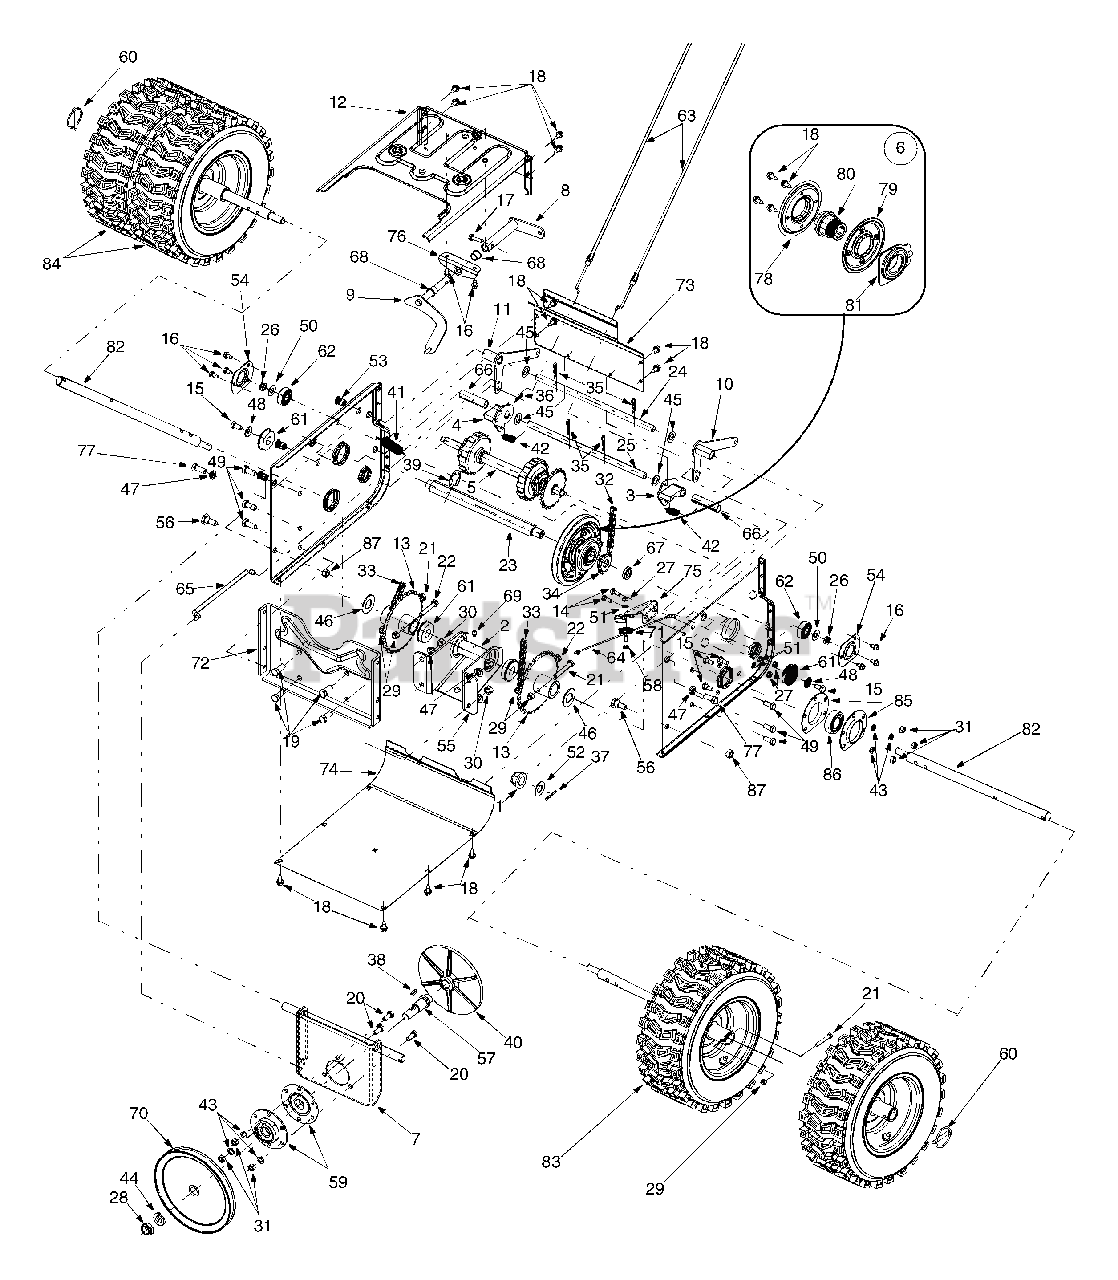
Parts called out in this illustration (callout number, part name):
1	Hex Flange Bearing
2	Spacer,.6725 x 1.125 x 2.485
3	Dogg Assembly LH
4	Dogg Assembly RH
5	Drive Shaft Assembly
6	Friction Wheel Assembly
9	Shift Rod Assembly
10	Auger Actuator Bracket Assy.
14	Hex Screw, 1/4-28 x.625"
15	Hex Screw, 5/16-18 x.625"
16	Self-tapping Screw, 1/4-20 x.5
17	Self-tapping Screw, 1/4-20 x 1"
18	Self-tapping Screw, 1/4-14 x.625"
19	Hex Screw 3/8-16 x .880"
20	Hex Screw 5/16-18 x .75"
21	Hex Screw 5/16-18 x 2"
22	Hex Screw 5/16-18 x 1.75"
23	Hex Drive Shaft
24	Actuator Shaft
25	Actuator Drive Shaft
27	Hex Nut 1/4-28
28	Jam Lock Nut
29	Flange Lock Nut, 5/16-18
30	Hex Nut 3/8-16
31	Hex Nut 5/16-18
34	Sprocket, 10T
35	Hairpin Clip
36	Hairpin Clip
37	Cotter Pin
38	Key
39	Retainer Ring
40	Drive Plate
41	Extension Spring
42	Extension Spring
43	Lock Washer 5/16
44	Lock Washer 5/8
45	Flat Washer
46	Flat Washer
47	Lock Washer
48	Bell Washer
49	Self-tapping Screw, 5/16-12 x.750
50	Flat Washer
51	Lock Washer
52	Flat Washer
53	Nut Insert, 3/8-16
54	Bearing Retainer Bracket
56	Shoulder Screw
57	Drive Plate Spindle
58	Shoulder Screw 1/4-28 x .375"
59	Bearing Housing Assembly
61	Ball Bearing
62	Ball Bearing
63	Steer Cable
64	Auger Idler Cable
65	Drive Clutch Rod
66	Split Spacer
67	Spacer
68	Flange Bearing
69	Lube Fitting, 3/16
70	Drive Pulley
71	Roller Cable
78	Bonded Friction Wheel
79	Friction Wheel Plate
80	Friction Wheel Hub
81	Friction Wheel Bearing Assembly
82	Wheel Axle
83	Wheel Assembly, LH
85	Bearing Housing
86	Self Aligning Bearing
87	Flange Lock Nut, 3/8-16
